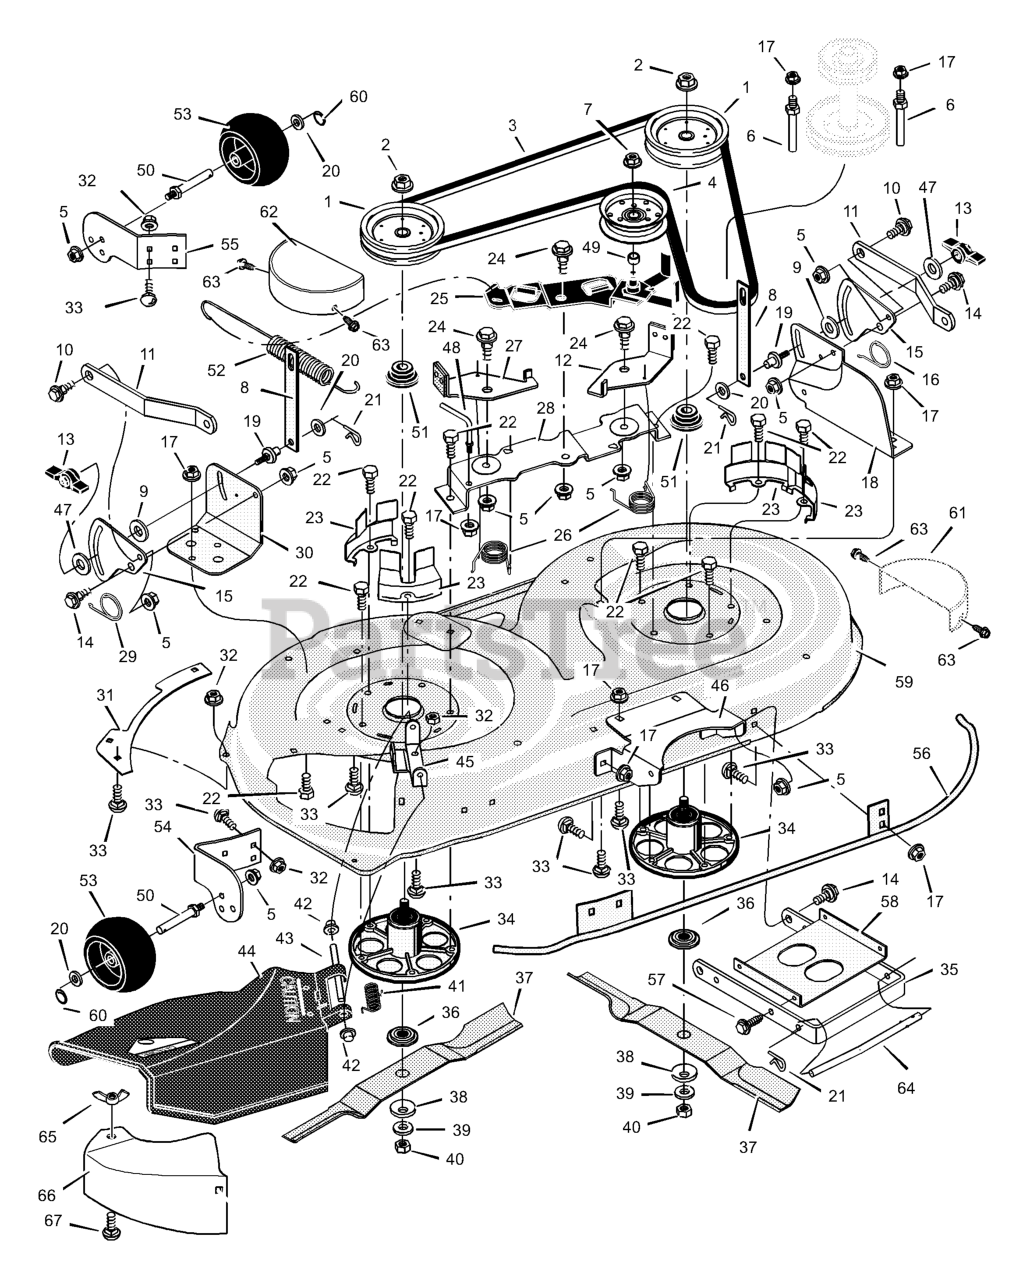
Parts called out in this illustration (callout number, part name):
1	Pulley, Jackshaft
2	Nut, Hex
3	Belt, Mower Drive
4	Pulley, Idler
5	Nut, Flange
6	Guide, Belt
7	Nut, Flange
8	Link, Lift
9	Pad, Friction
10	Bolt, Shoulder
11	Bracket, Suspension
12	Pad Assembly, Left Brake
14	Bolt, Shoulder
15	Plate, Suspension
17	Nut, Flange
18	Bracket, Suspension
19	Pin, Hanger
21	Pin, Hair
22	Bolt
23	Cover, Pulley
24	Bolt, Shoulder
25	Arm, Idler
27	Pad Assembly, Right Brake
28	Bracket, Brake
30	Bracket, Suspension
32	Nut, Flange
33	Bolt, Carriage
34	Mandrell Housing
35	Bracket, Suspension
36	Adapter, Blade
38	Washer
39	Washer
40	Nut
42	Cap, Push On
43	ROD, Deflector
44	Deflector Assembly
45	Bracket, Deflector Hinge
46	Bracket, Front Hanger
48	Guide, Belt
50	BOLT, Gauge Wheel
51	Spacer, Pulley
52	Spring, Extension
53	Wheel, Gauge
54	Bracket, Right Wheel
55	Bracket, Left Wheel
56	Reinforcement Assembly
58	Stiffener
59	Housing, Blade
60	Ring, Locking
61	GUARD, Pulley L.H.
62	GUARD, Belt R.H.
64	Rod, Front Hanger
65	Wingnut
66	Plate, Mulch
67	Bolt, Carriage
